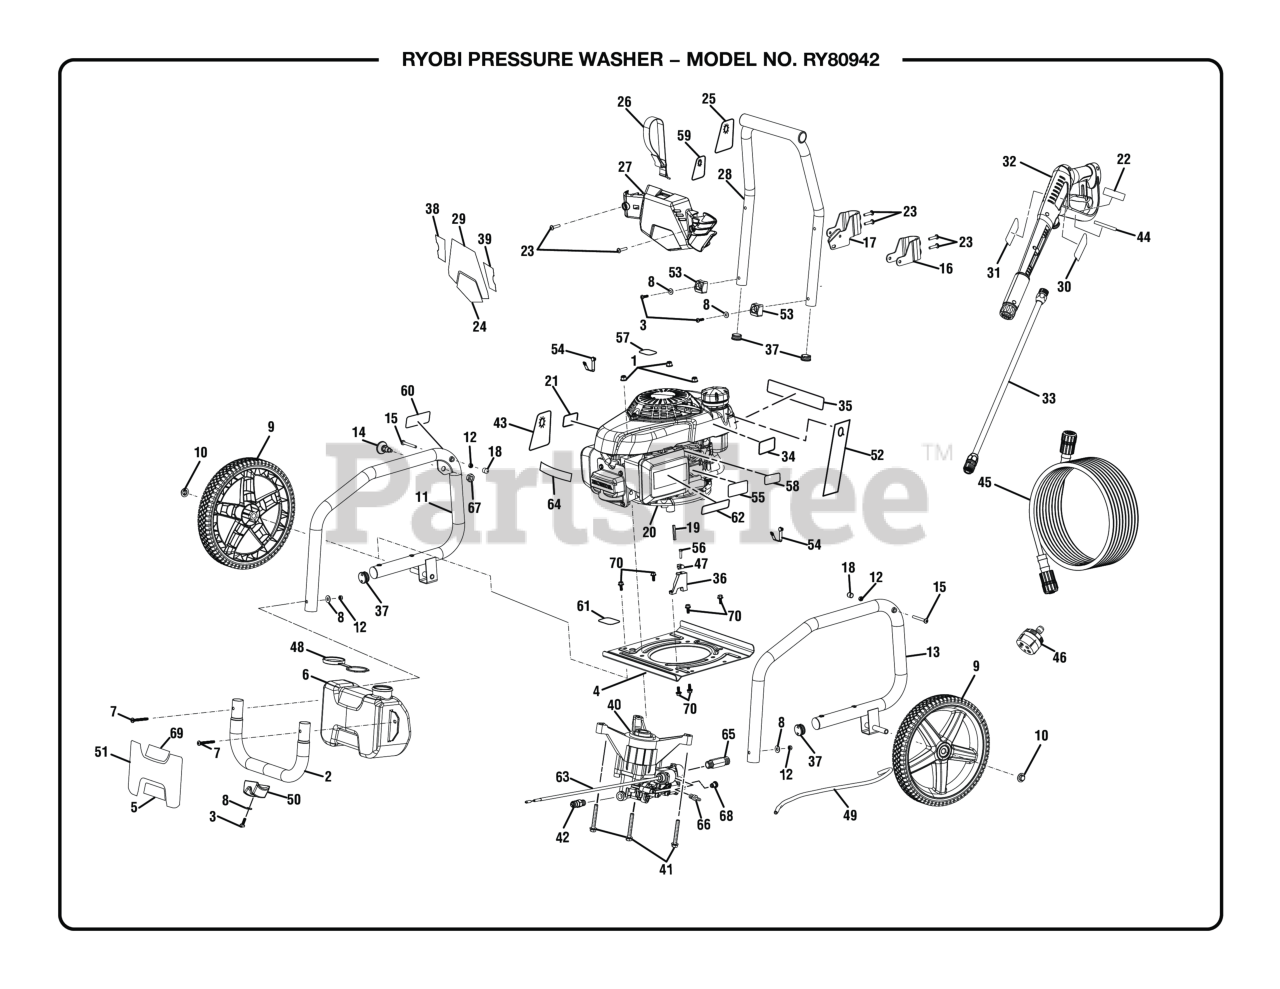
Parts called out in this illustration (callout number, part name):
1	Lock Nut (M8 x 1.25 mm, Flange)
2	Front Frame Assembly
3	Screw (M6 x 1.25in., T30 Torx Pan Hd.)
4	Engine Plate
5	Detergent Tank Label
6	Detergent Tank w/Outlet
7	Screw (M6 x 50 mm, T30 Torx Pan Hd. )
8	Washer (1/4 in.)
9	Wheel
10	Push Cap Nut (1/2 in.)
11	Main Frame Assembly
12	Lock Nut (M6 x 1)
13	Main Frame Assembly
14	Handle Lock Assembly
15	Connection Pin (1/4-20 x 3.5 in., Hex Hd.)
16	Handle Connector (Left)
17	Handle Connector (Right)
19	Output Shaft Key (3/16 in. x 40 mm)
21	Hot Surface and Exhaust Label
22	Label (Trigger Handle Warning, French & Spanish)
23	Bolt (M6 x 25 mm,T30 Torx Pan Hd.)
24	Performance Label
25	Quick Start Hangtag
26	Hose Holder Strap
27	Hose & Wand Storage
28	Handle Assembly
29	Warning Icon Label
30	Trigger Handle Warning Label (English)
31	LABEL, TRIGGER HANDLE LOGO
32	Trigger Handle Assembly
33	Extension Wand
34	No E85 Label
35	Danger Label (English/French)
36	Idle Down Cable Bracket
37	Plastic Tube Cap
38	Wing Label (Left)
39	Wing Label (Right)
40	Pump
41	Flange Bolt (M8 x 1.25 x 60 mm, Hex Hd.)
42	Thermal Release Valve.
43	Label (Oil Dipstick Hangtag)
44	LABEL, TRIGGER HANDLE RATING, EN FR SP
45	High Pressure Hose (50 ft.)
46	5-in-1 Change Over Nozzle
47	Idle Down Cable Clamp
48	Detergent Tank Cap
49	Injection Hose
50	Rubber Foot
51	Honda Logo Label
52	Danger Hangtag
53	Rubber Bumper
54	Lock Button w/Spring Clip
55	Engine Control Label
56	Cap Screw (M5 x 20 mm)
57	Combustion Warning Label (English/French)
58	On/Off Label
59	5- In- 1 Nozzle Hangtag
60	Handle Release Label
61	Oil Fill Location Label
62	Inquires Label (Ryobi)
63	Idler Assembly
64	Idle Down Label
65	Outlet Tube
66	Detergent Injector Assembly
67	Lock Nut (1/2-20, Hex)
68	Inlet Filter Adapter/Brass Insert
69	Logo Label
70	Flange Bolt (M6 x 1 x 16 mm, Hex Hd.)
